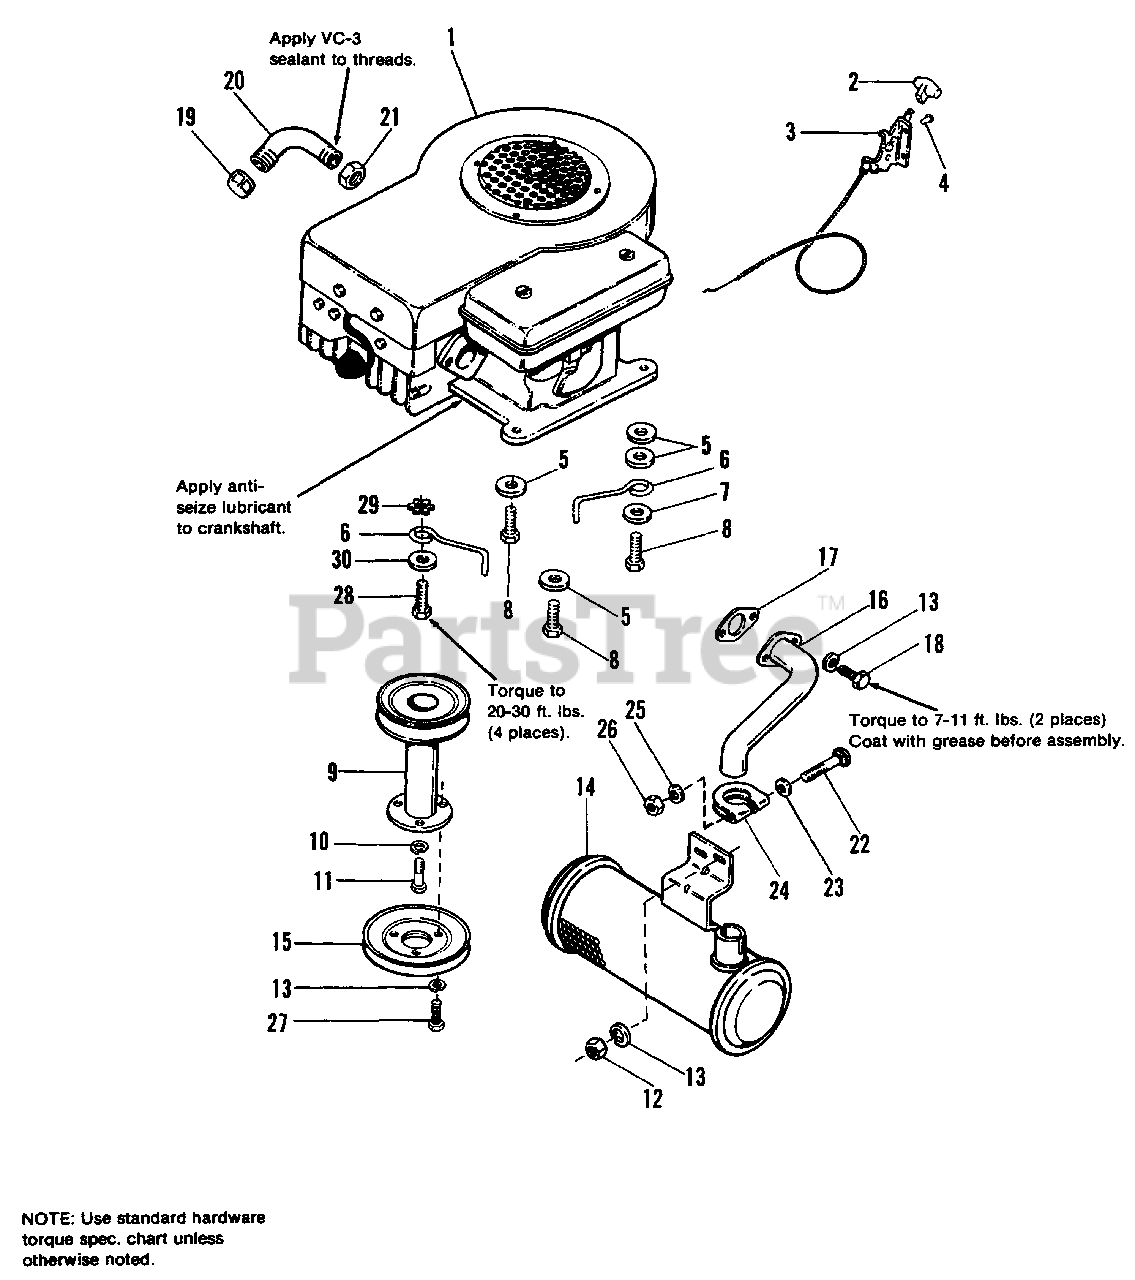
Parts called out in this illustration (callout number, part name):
1	ENGINE, 11 HP, Briggs & Stratton
2	KNOB, Throttle
3	CONTROL ASSY., Throttle
4	RIVET, Pop, 1/4
5	WASHER, Plain, 3/8
7	WASHER, 3/8
8	SCREW, Taptite, 3/8-16 x 1-1/2
9	PULLEY ASSY., Engine
10	LOCKWASHER, 7/16
11	CAPSCREW, Hex, 7/16-20 x 1-1/4
12	NUT, Hex, 5/16-18
13	LOCKWASHER, 5/16
16	PIPE, Exhaust
17	GASKET, Muffler
18	CAPSREW. Hex, 5/16-18 x 3/4
20	PIPE, Oil Drain (Incl. Ref. Nos. 19 & 21)
21	LOCKNUT, Conduit
22	BOLT, Carriage 5/16-18 x 3-2//4
23	WASHER, 5/16
25	LOCKWASHER. 5/16
26	NUT, Hex, 5/16-18
27	CAPSCREW, Hex Hd., 5/16-18 x 1-1/2 Full Thrd.
28	SCREW, Taptite, 3/8-16 x 1-1/2 Zinc Plt.
29	LOCKWASHER, Ext., 3/8, Zinc Plt.
30	WASHER, 3/8 Zinc Plt.
